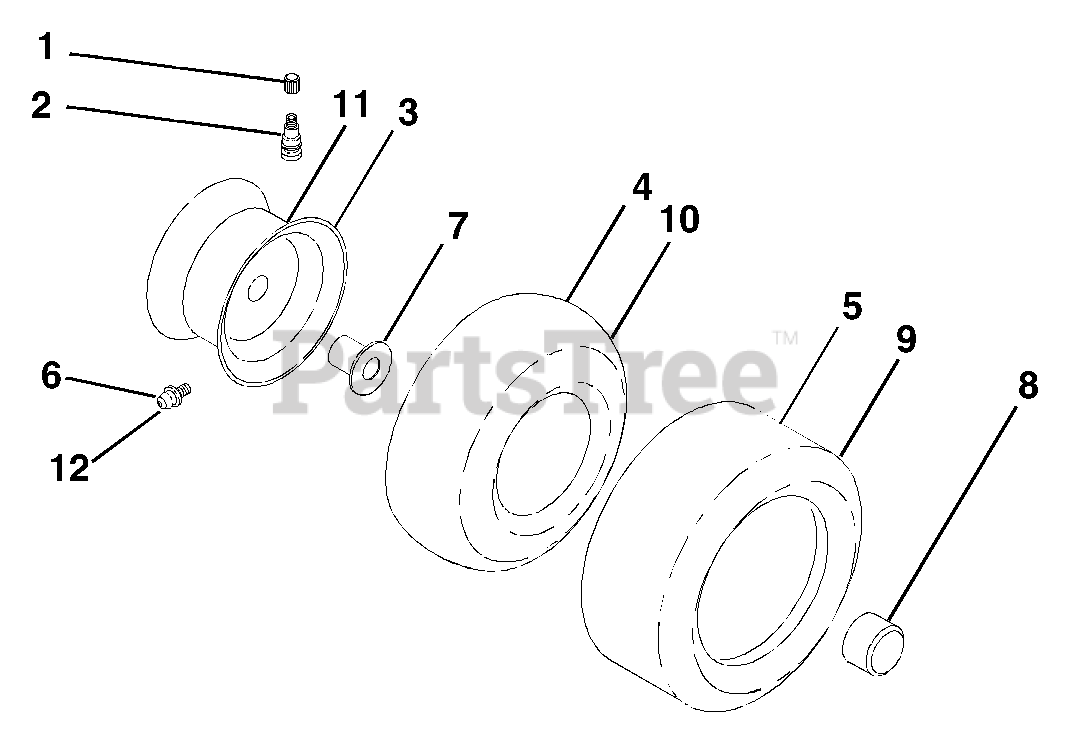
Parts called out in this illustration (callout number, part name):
1	Cap, Valve, Tire
2	Stem, Valve
3	Rim Assembly, Front
4	Tube, Front
5	Tire, Front
6	Fitting, Grease
7	Bearing, Flange
8	Cap, Axle
9	Tire, Rear
10	Tube, Rear
11	Rim Assembly, Rear
12	Fitting, Grease
